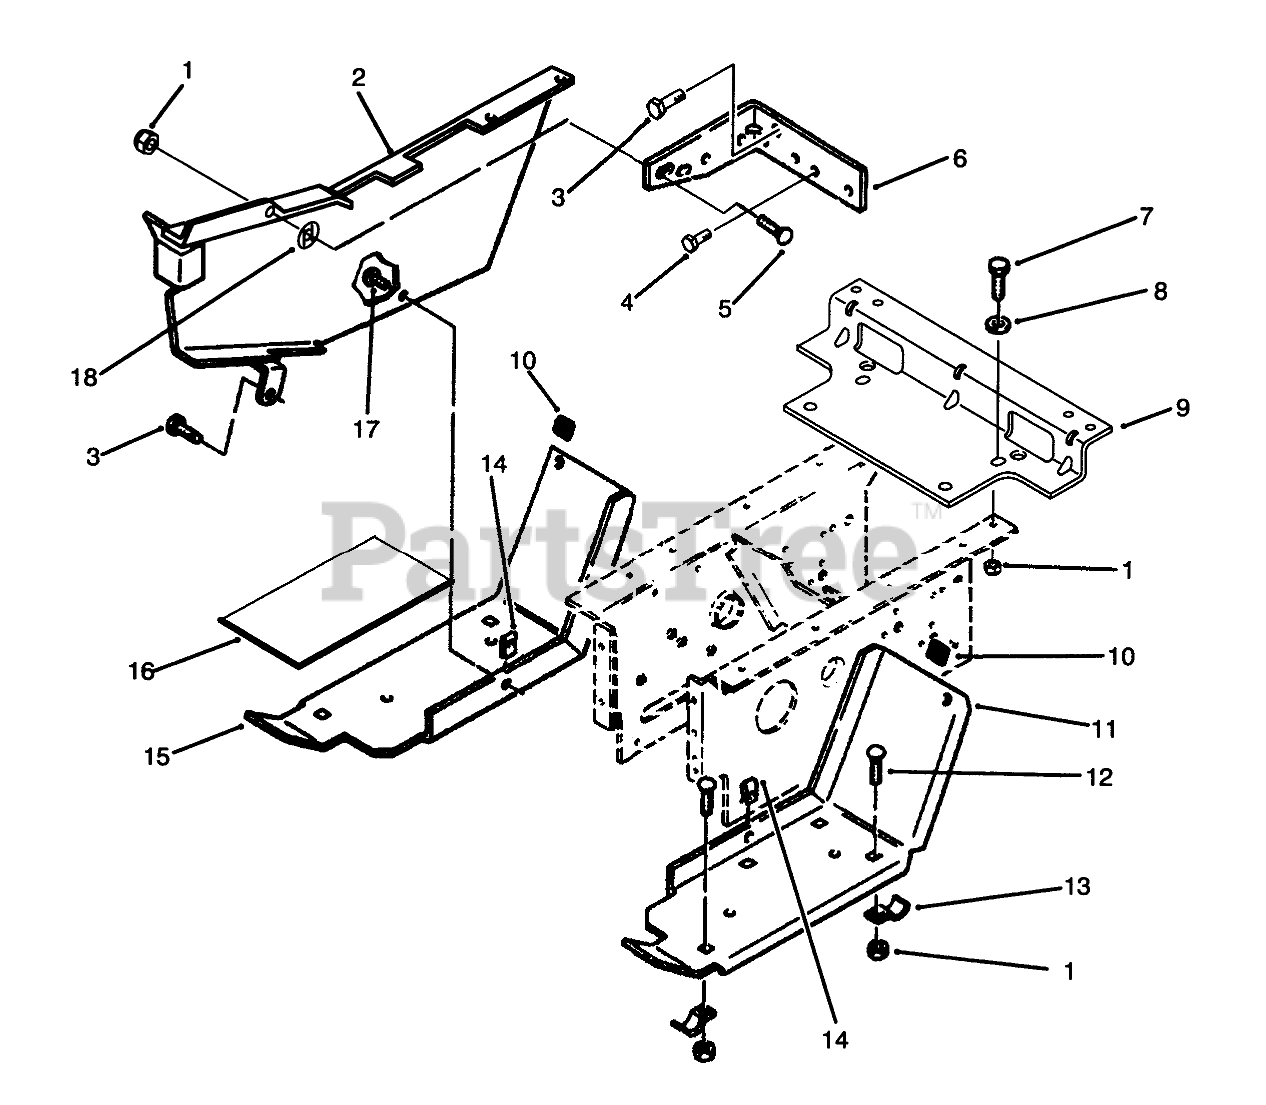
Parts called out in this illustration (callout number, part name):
1	NUT-LOCK, NI
2	GUARD - BELT WA R
3	SCREW
4	Bolt
5	BOLT-CARR
6	BRACKET-BELTB
7	SCREW-HH
8	WASHER-PLAIN
9	Bracket-Fender
10	BUMPER
11	FOOTREST LH R
12	BOLT-CARR
13	BRACKET
15	Footrest-RH
16	PAD FOOTREST
17	Screw
18	NUT-PUSH
